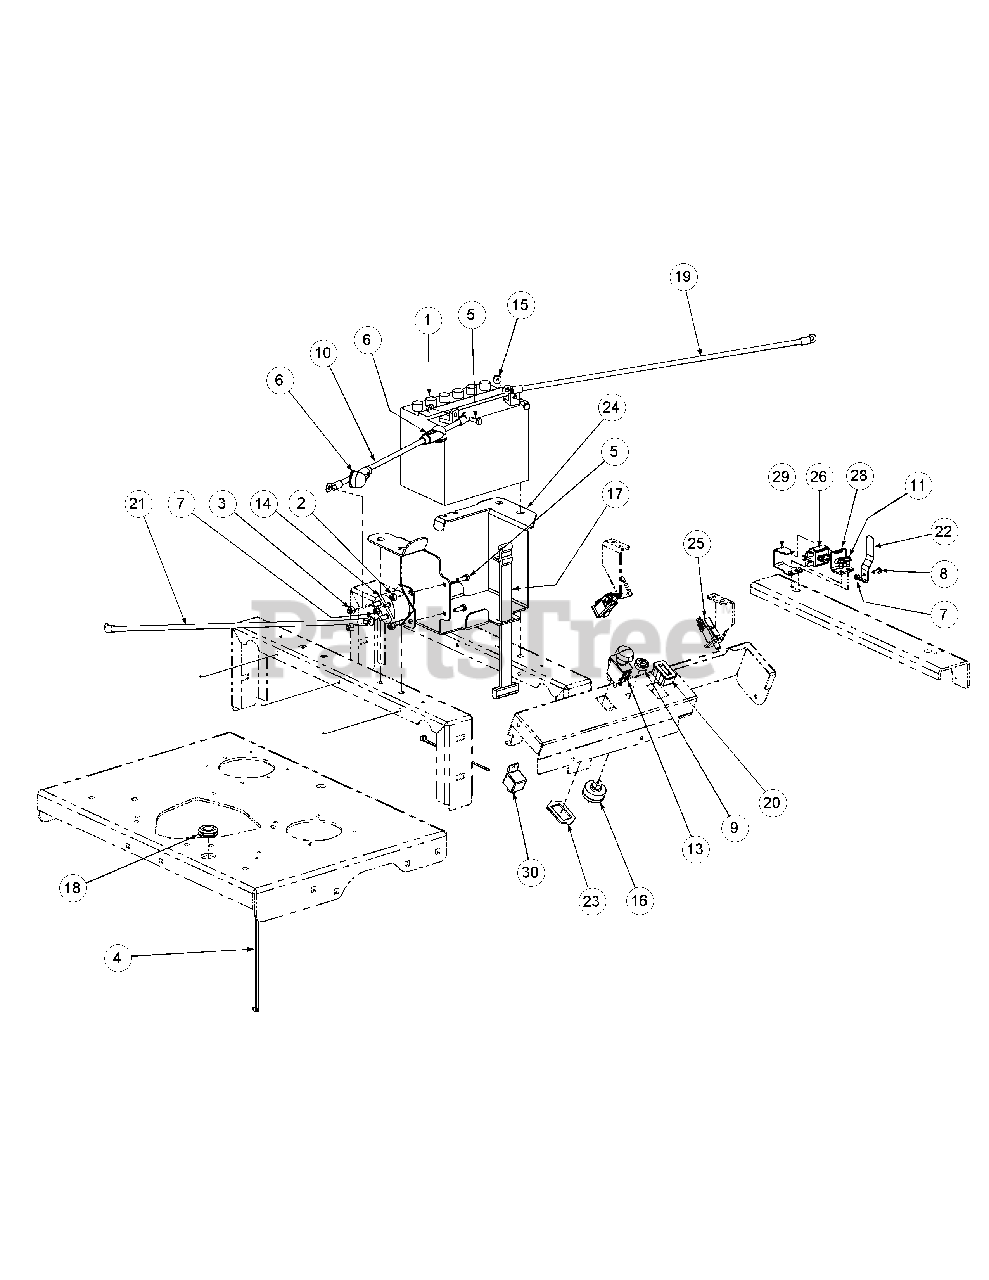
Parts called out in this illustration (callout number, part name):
1	Battery, 12V 225CCA 30 Min
2	Lock Nut w/Nylon Insert
3	Nylock Nut, 5/16-18
4	Tie, Cable, 3/16 x .05 x 7.4"
5	Screw, Hex, Cap, 1/4-20 x .75
6	Boot, 1" OD Rubber Battery-PST, Red
7	Nut, Lock, Nylon Insert, #10-32
8	Screw, Hex Washer, 10-32 x 1/2
9	Nut, W/Cap, 5/8-32 Ignition
10	Cable, Battery, Red, 15"
11	Screw, TT, 1/4-20, 0.5, Hex Index Washer
13	Switch, Electric, PTO
14	Solenoid Magnetic Switch
15	Hex Flange Lock Nut, 1/4-20
16	Switch, Ignition, 6 Pin
17	Strap, Battery
18	Grommet, .75 ID
19	Cable, Battery Black, 28"
20	Meter, Hour
21	Cable, Battery Red, 32"
22	Spring Retainer
23	Bracket, PTO Switch Retainer
24	Mount Bracket, Battery
25	Switch, Safety N.O./N.C.
26	Switch, Plunger
28	Bracket, Plunger Switch
29	Clamp, Plunger Switch
30	Relay, 12V 40A
